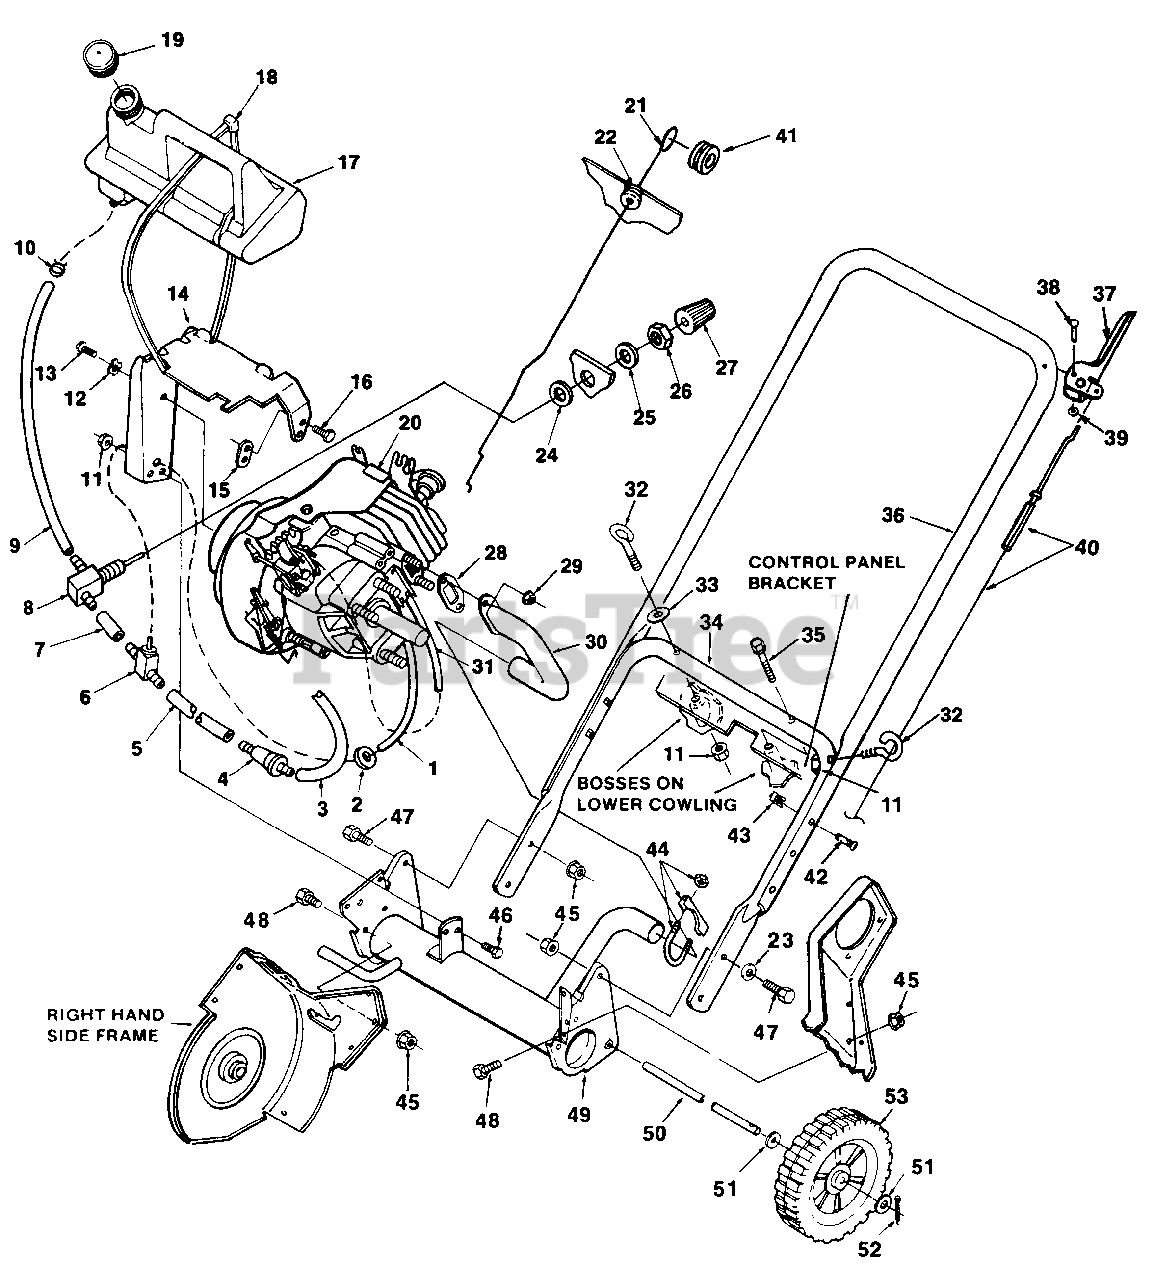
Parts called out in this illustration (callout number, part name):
1	TUBING- Rubber 17"
3	TUBING- Rubber (cut to 8")
4	FILTER-Fuel
5	TUBING- Rubber (13 1/2")
6	FITTING- Fuel
7	TUBING- Rubber (cut to 1 1/2")
9	TUBING- Rubber (cut to 7 1/4")
11	NUT- Flange 1/4-20
12	WASHER- Shakeproof 1/4"
13	BOLT- 1/4-20 x 3/8
14	BRACKET- Fuel tank
16	SCREW- 10-24 x 3/4
17	FUEL TANK
18	EYEBOLT AND NUT ASSY.
19	CAP- Tank
20	SHORT BLOCK
21	ROD- Choke
23	WASHER- 5/16
24	WASHER- Flat 7/16
25	WASHER- Lock 7/16
26	NUT- R.H. 7/16-20
27	KNOB- Shut off
28	GASKET- Manifold
29	NUT- 10-32
30	MANIFOLD- Exhaust
31	RUBBER TUBING (cut to 11 1/4")
33	WASHER- 1/4"
34	HANDLE- Lower
35	SCREW- #10-16 x 1 1/2"
36	HANDLE- Upper
37	LEVER- Operating
40	CABLE & SPRING
42	SCREW- 1/4-20 x 1 1/2"
43	RETAINER- Nut 1/4-20
44	CLAMP- Muffler
45	NUT- Flange 5/16-18
46	SCREW- 1/4-20 x 1/2
47	SCREW- 5/16-18 x 3/4
48	SCREW- Cap 5/16-18 x 5/8"
50	AXLE-Shaft
51	WASHER- Flat 3/8"
52	PIN- Cotter 3/32-34
53	WHEEL & TIRE
